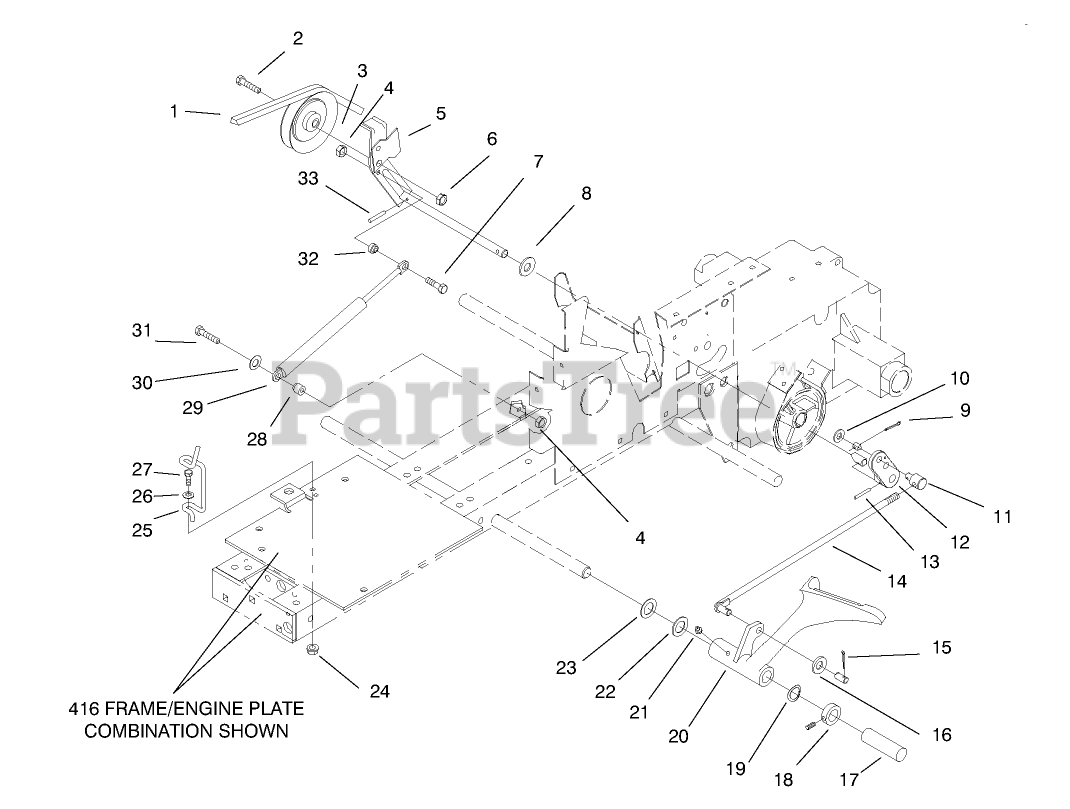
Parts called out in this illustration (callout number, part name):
1	BELT - V
2	BOLT-SPECIAL HEX
3	PULLEY-IDLER
4	NUT-LOCK, NI
5	ASM-Clutch Idler Arm
6	NUT-HEX
7	Capscrew
8	SHIM-WASHER
9	PIN-COTTER
10	WASHER-FLAT
11	TRUNNION
12	Arm-Clutch Rod
13	PIN-SPIROL
14	ROD AND GUIDE ASM
15	PIN-COTTER
16	WASHER-NYLON
17	SLEEVE-PROTECTIVE
18	COLLAR
19	WASHER-BOWED
20	PEDAL-BRAKE, CLUTCH
21	FITTING-GREASE
22	WASHER
23	WASHER
24	NUT-LOCK, NI
25	Guide-Belt Bottom
26	WASHER-FLAT
27	SCREW-HH
28	SPACER-SHOULDER-.400
29	ASS'Y-GAS SPRING
30	WASHER-FLAT
31	SCREW-HH
32	SPACER-SHOULDER-.200
33	PIN-SPIROL
